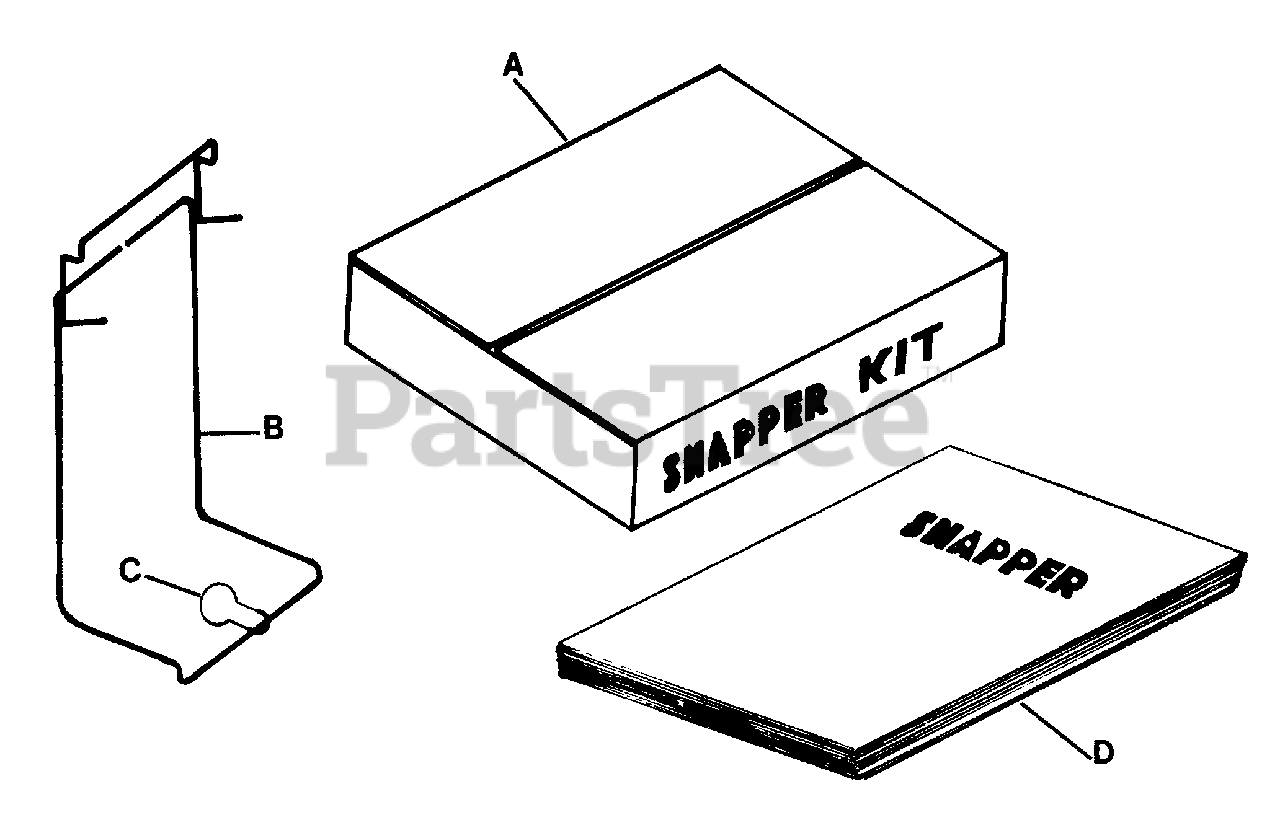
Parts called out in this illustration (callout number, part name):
A	KIT, Zip Bag
B	HOOP, Zip Bag
C	HOOK, Zip Bag
D	BAG, Snapper Trash
